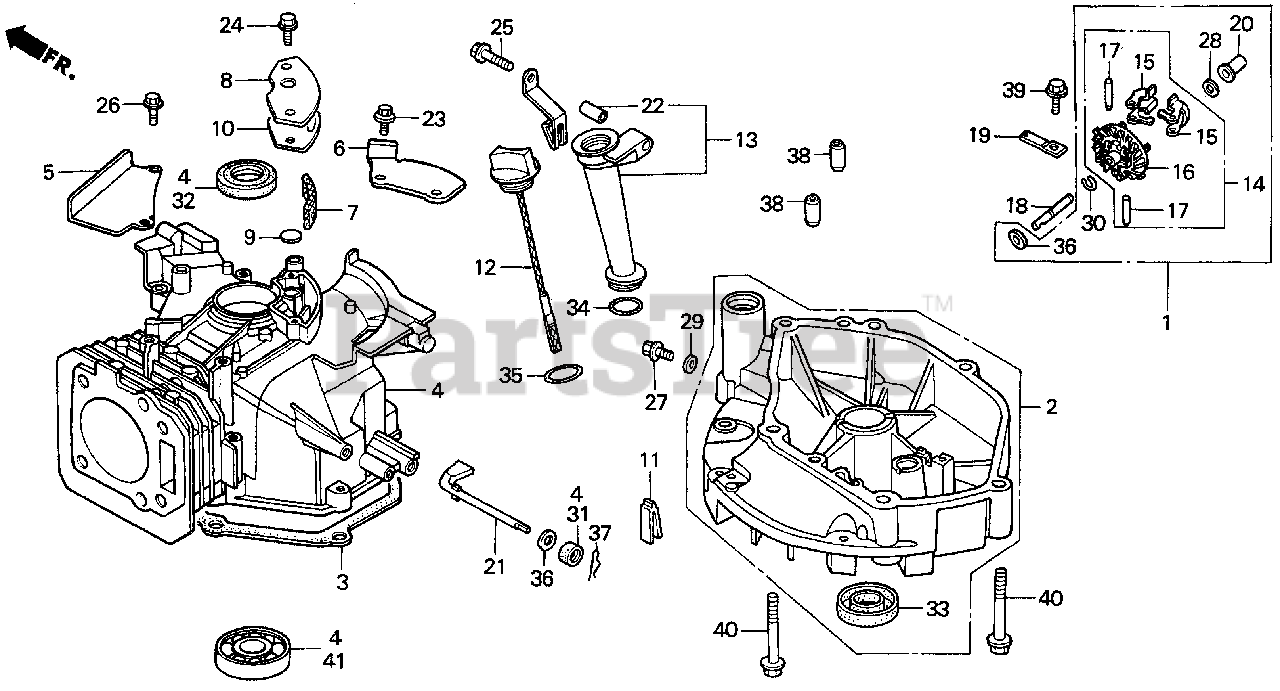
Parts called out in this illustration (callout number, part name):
1	GOVERNOR KIT
2	PAN ASSY., OIL (PUSH TYPE)
3	GASKET, OIL PAN
4	CYLINDER ASSY.
5	PLATE, GUIDE
6	PLATE A, GUIDE
7	FILTER, BREATHER
8	COVER, BREATHER
9	VALVE, BREATHER
10	GASKET, BREATHER COVER
11	RUBBER, OIL RETURN
12	DIPSTICK, OIL
13	EXTENSION, OIL FILLER (106MM)
14	GOVERNOR ASSY.
15	WEIGHT, GOVERNOR
16	HOLDER, GOVERNOR WEIGHT
17	PIN, GOVERNOR WEIGHT
18	SHAFT, GOVERNOR HOLDER
19	PLATE, GOVERNOR SHAFT HOLDER
20	SLIDER, GOVERNOR
21	SHAFT, GOVERNOR ARM
22	COLLAR, EXTENSION
23	BOLT, FLANGE (6X12) (CT200)
24	BOLT, FLANGE (6X14)
25	BOLT, FLANGE (6X32)
26	BOLT, FLANGE (6X20) (CT200)
27	BOLT, DRAIN PLUG
28	WASHER, THRUST (6MM)
29	WASHER, DRAIN PLUG (10.2MM)
30	CLIP, GOVERNOR HOLDER
31	OIL SEAL (6X11X4)
32	OIL SEAL (25X38X7)
32	OIL SEAL (25X38X7) (ARAI)
33	OIL SEAL (25.4X40X7)
34	O-RING (22.5X2.2)
35	O-RING (26X2.7)
36	WASHER, PLAIN (6MM)
37	PIN, LOCK (8MM)
38	PIN A, DOWEL (8X14)
39	BOLT, FLANGE (6X12)
40	BOLT, FLANGE (8X50)
41	BEARING, RADIAL BALL (6205)
